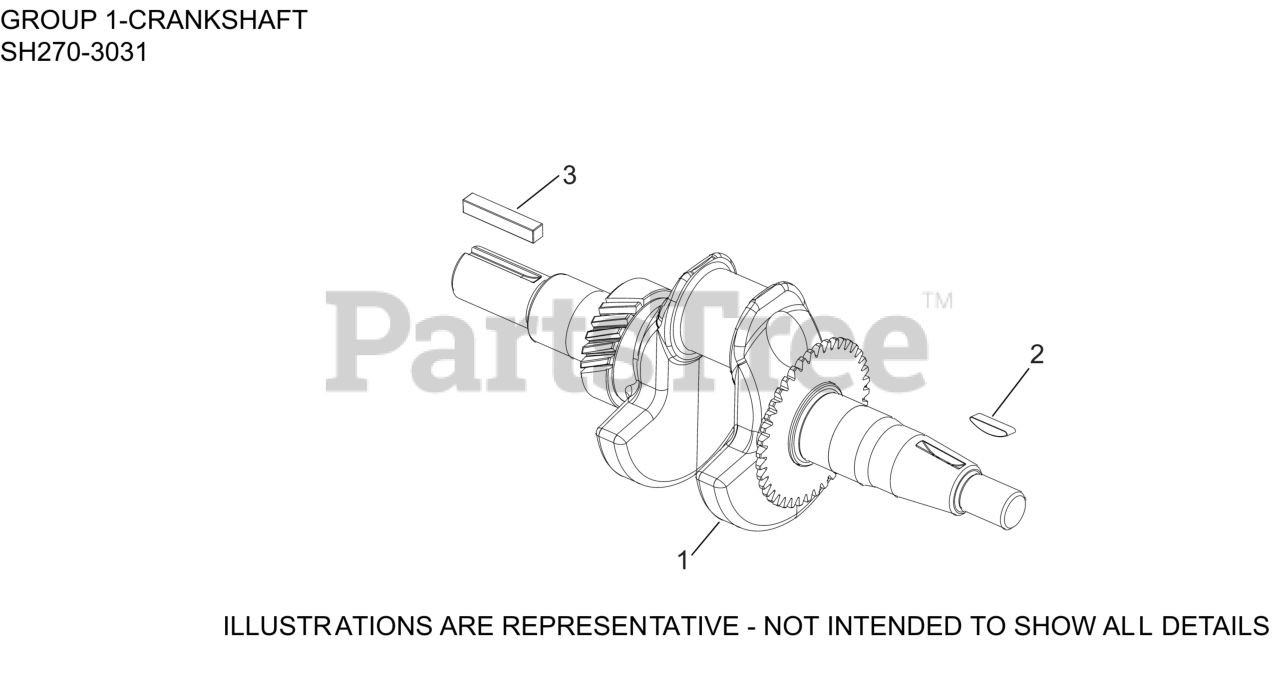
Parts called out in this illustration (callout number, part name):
1	CRANKSHAFT ASSEMBLY
2	KEY, FLYWHEEL
3	KEY, SQUARE
